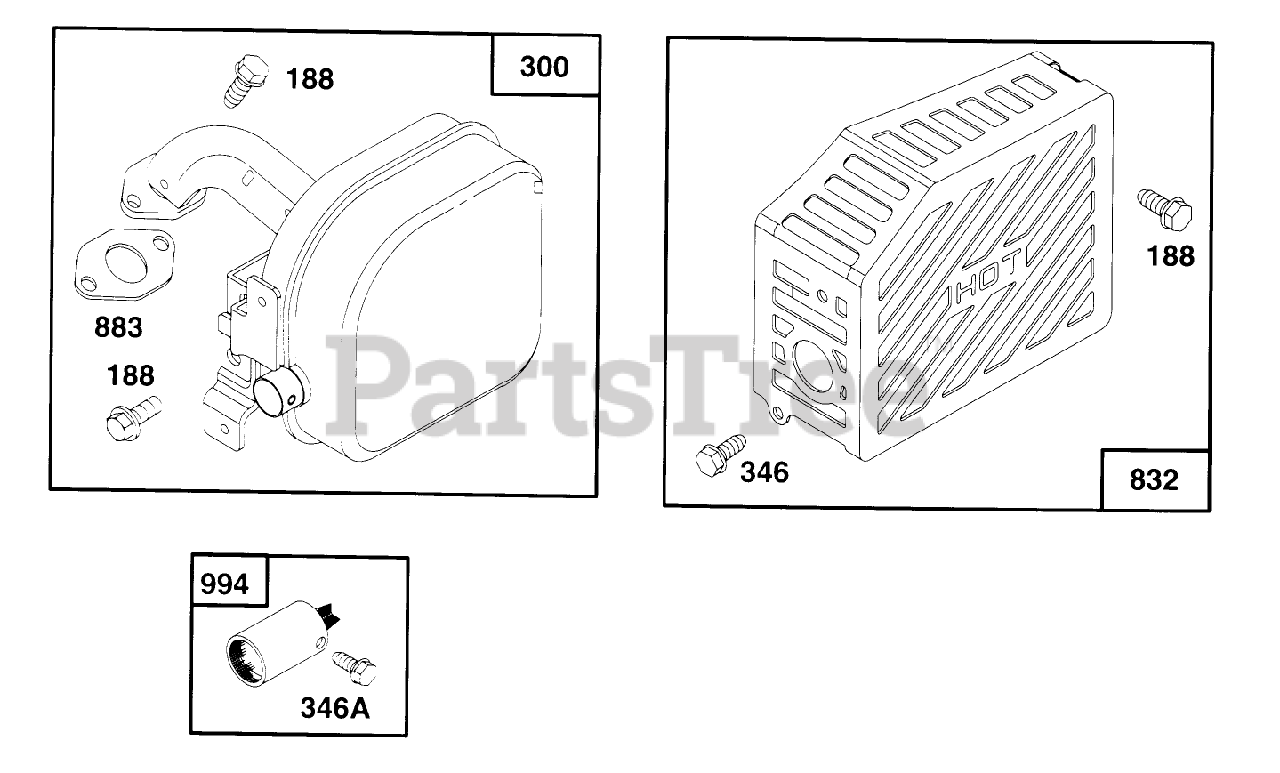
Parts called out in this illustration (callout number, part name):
188	SCREW - SEM
300	MUFFLER - EXHAUST
346	SCREW - SELF-TAPPING
